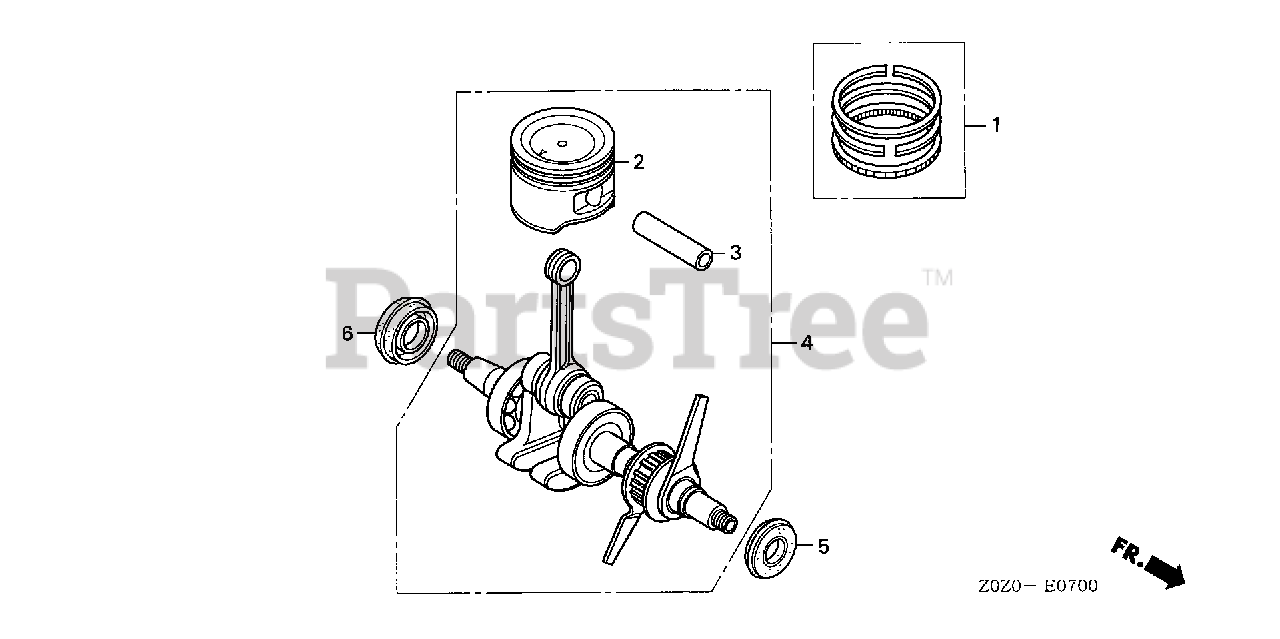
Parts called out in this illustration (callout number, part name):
1	RING SET, PISTON
2	PISTON (NOT AVAILABLE)
2	PISTON
3	PIN, PISTON
4	CRANKSHAFT
5	OIL SEAL (10X20X5)
6	OIL SEAL (15X25X6)
